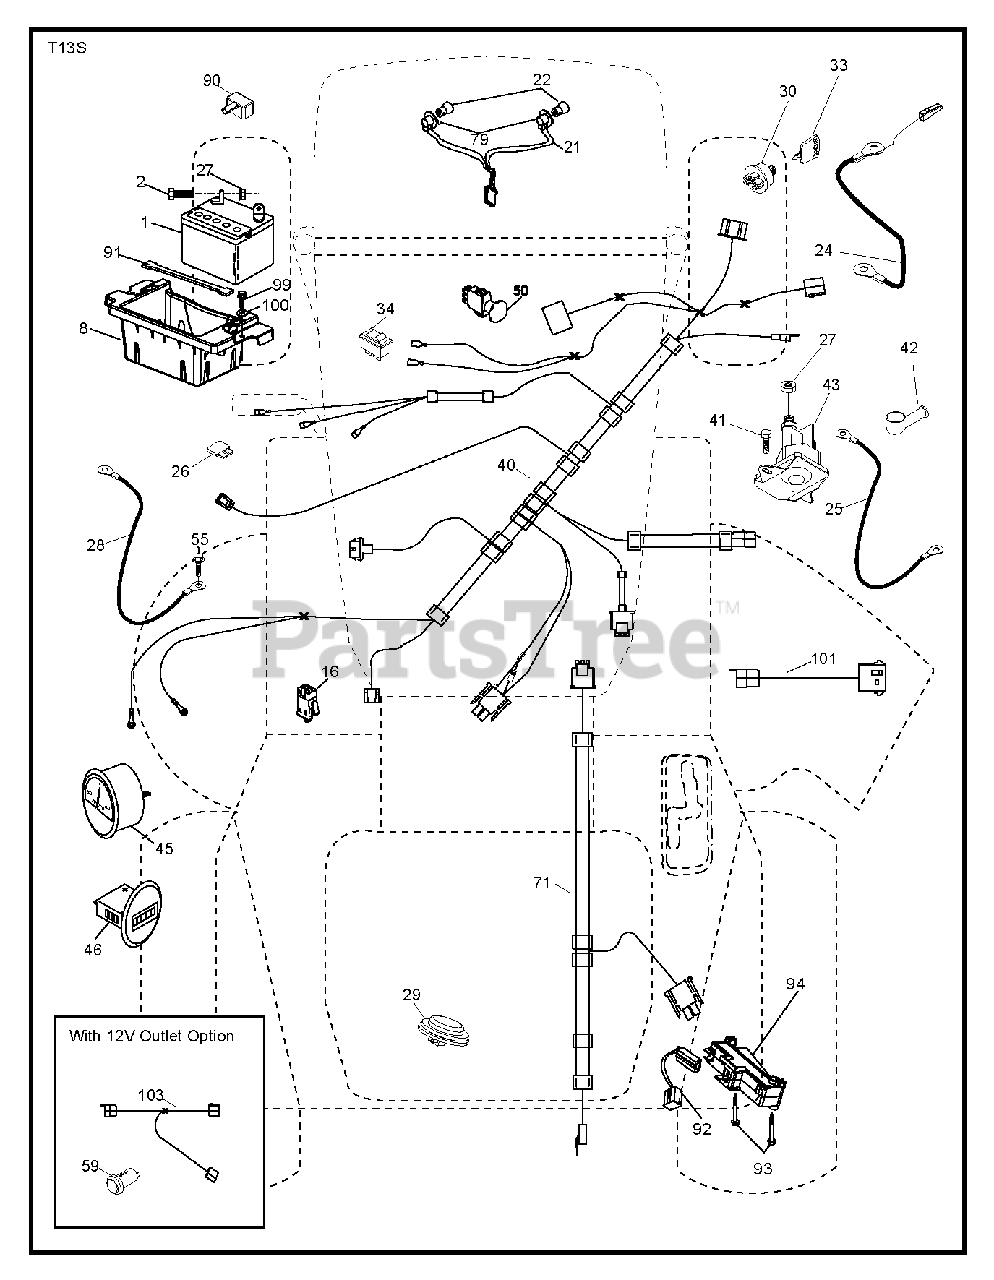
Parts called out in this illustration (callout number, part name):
1	REPL BY 532 12 38-99
8	BOX.BATTERY.MOUNT.FRONT.LT
16	SWITCH INTERLOOK PUSH-IN
21	HARNESS.W/LIGHT SOCKET
22	LIGHTBULB
24	CABLE.BATT.POS.WIRE.TG.DA SOL
25	CABLE.START.RED.17.5".
26	FUSE 20AMP
27	NUT
28	CABLE GROUND 6 GA 21" 90T BLK
29	SWITCH.SEAT.DELTA.OPC.
30	SWITCH.IGN.DELTA.W.LGH.ROS
33	KEY.CHAIN.BLISTER.PACK.GEN.INT
34	SWITCH LT
40	HARNESS IGN. DASH
41	SCREW
42	TERMINAL COVER
43	SOLENOID.W/BRASS.PLUNG
46	HOURMETER SNAP-IN
50	PTO SWITCH
55	SCREW 5/16"
71	HARNESS-CHASSIS SUB
79	BULB HOLDER ASM.
90	COVER.TERMINAL.BATTERY
91	STRAP, BATTERY MOUNT
92	HARNESS.PIGTAIL.CONSLE
93	SCREW.PLASTITE
94	MODULE.REVERSE.ROS
99	SCREW HEXWSHR 1/4-20X3/4
101	PIGTAIL.MATNLK.NEW.HAR
